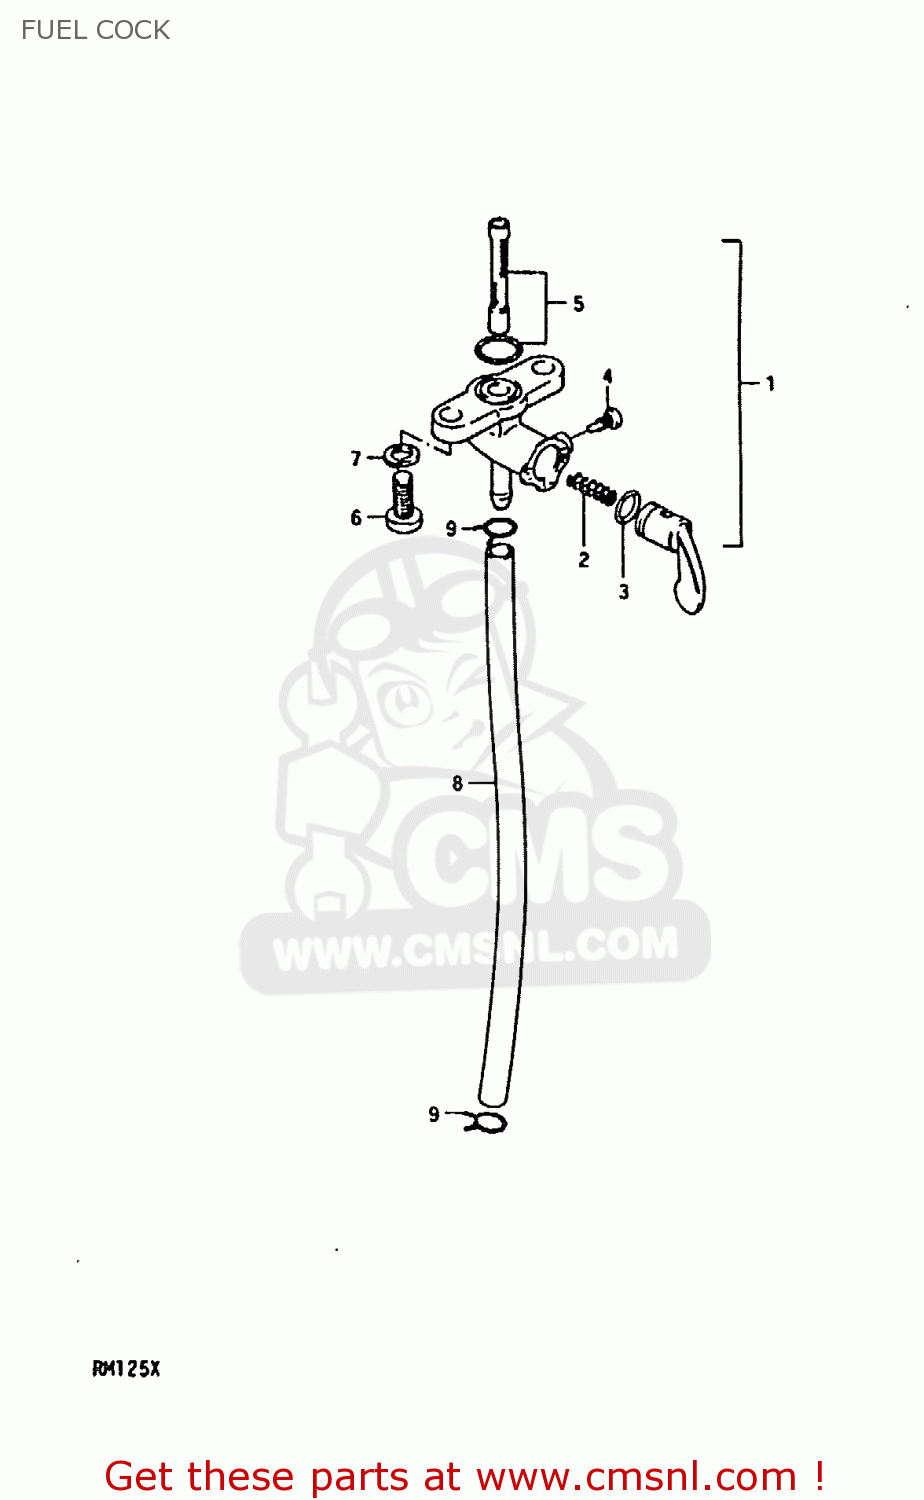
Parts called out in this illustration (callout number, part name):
1	COCK ASSEMBLY,FUEL
2	SPRING,FUEL COCK VALUE
3	O RING,LEVER
4	SCREW
5	FILTER SET FUEL
6	SCREW
7	LOCK WASHER
8	HOSE
9	CLIP
